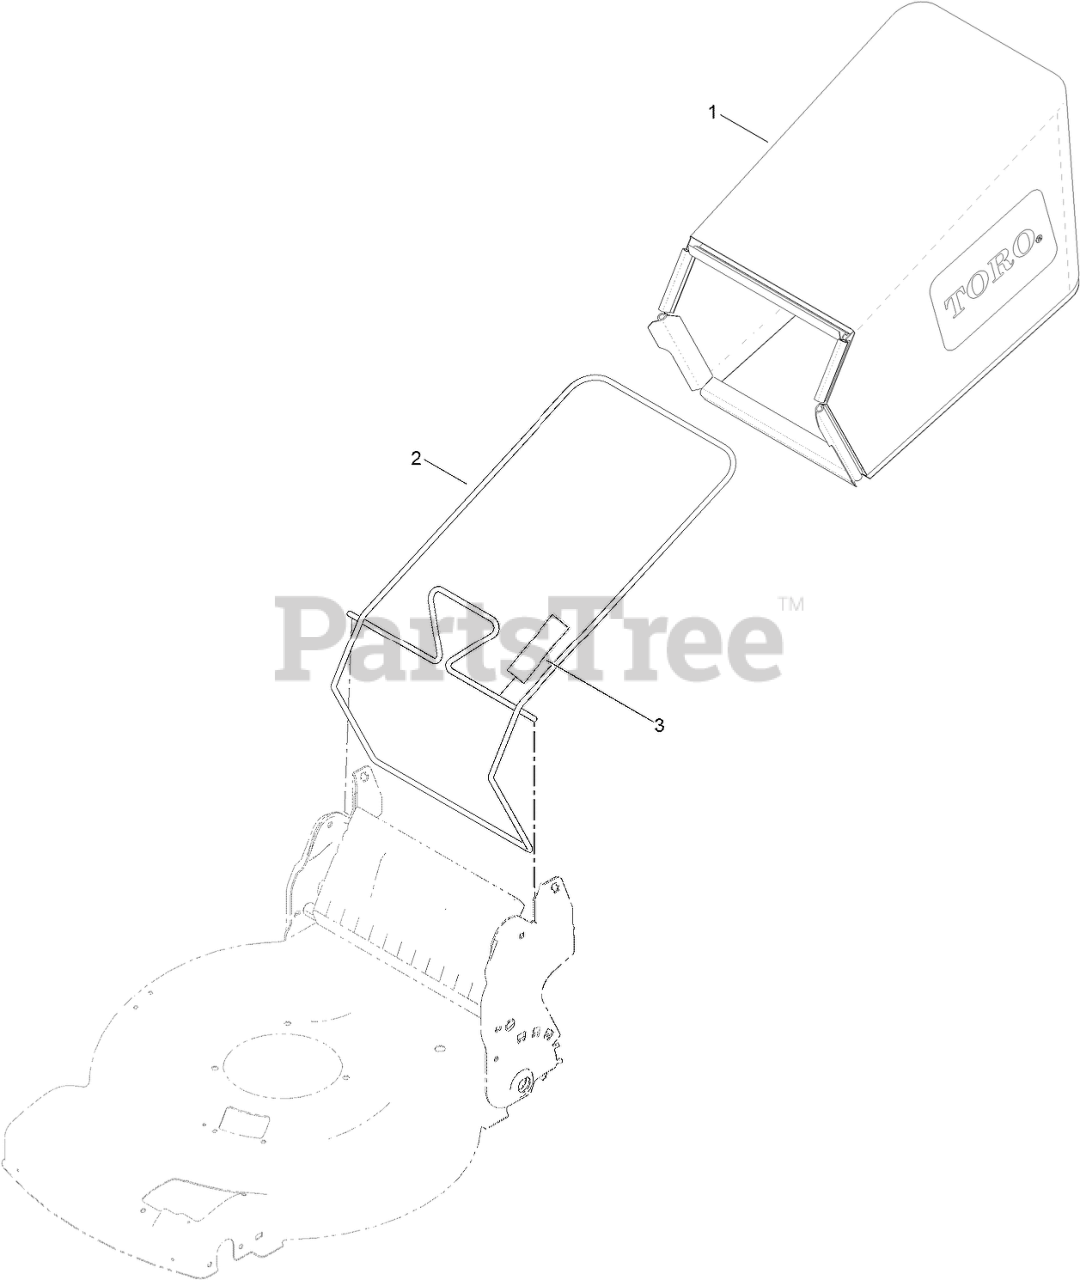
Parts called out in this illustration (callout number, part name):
1	GRASS BAG ASM
2	FRAME-BAG
3	Decal-Warning
